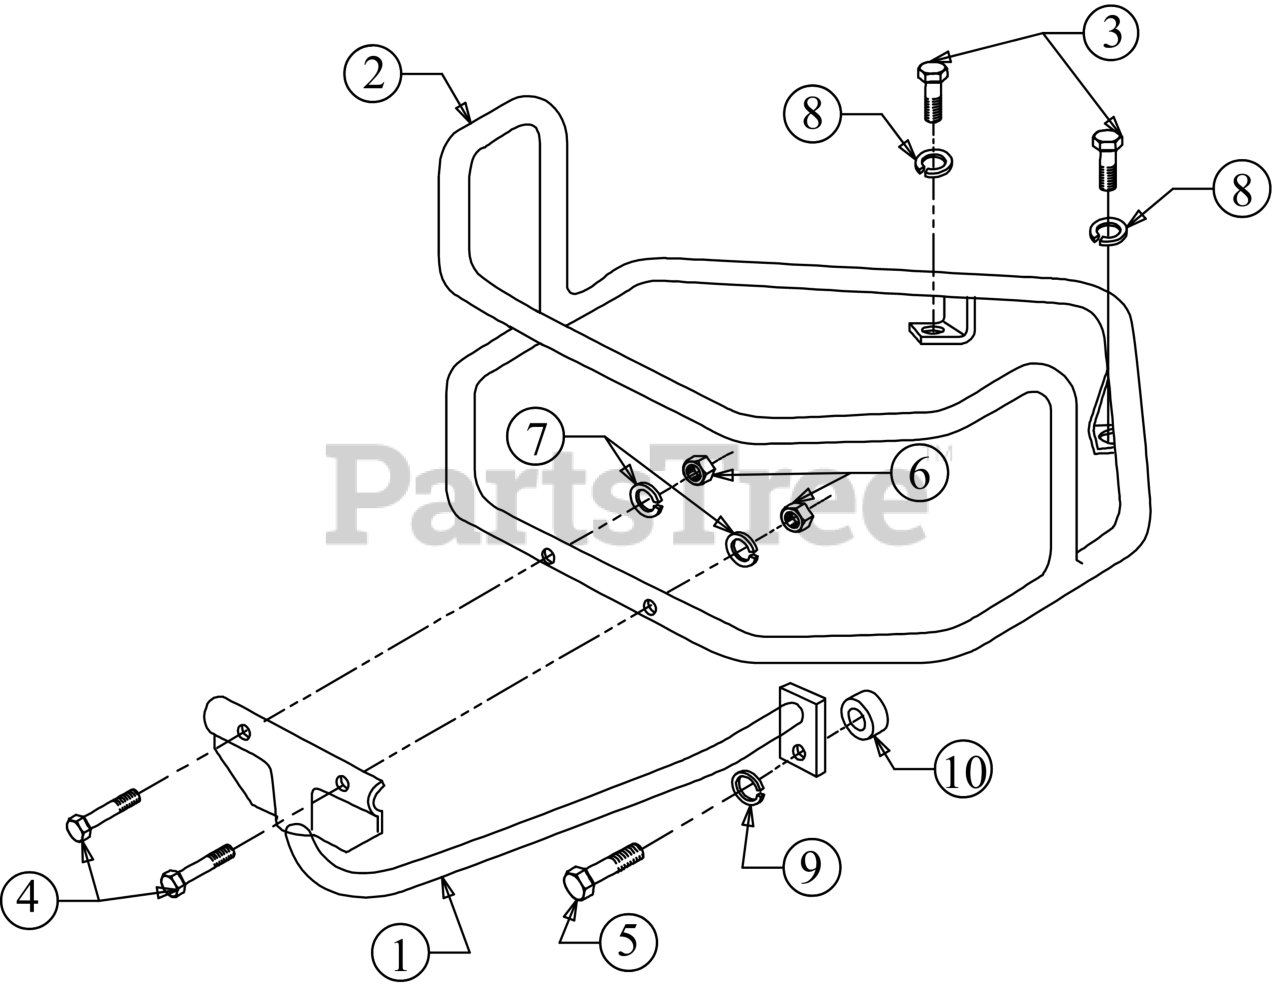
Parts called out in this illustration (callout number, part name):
1	BRACE-BUMPER B
2	GAURD-BUMPER-WRAP
3	SCREW 3/8-16 X GR5
4	SCREW 5/16-18 X 1.50 GR5
5	SCREW 1/2-13 X 1.50 GR5
6	HEX NUT
7	LOCK WASHER 5/16
8	LOCK WASHER 3/8
9	LOCK WASHER 1/2
10	BRACE SPACER
